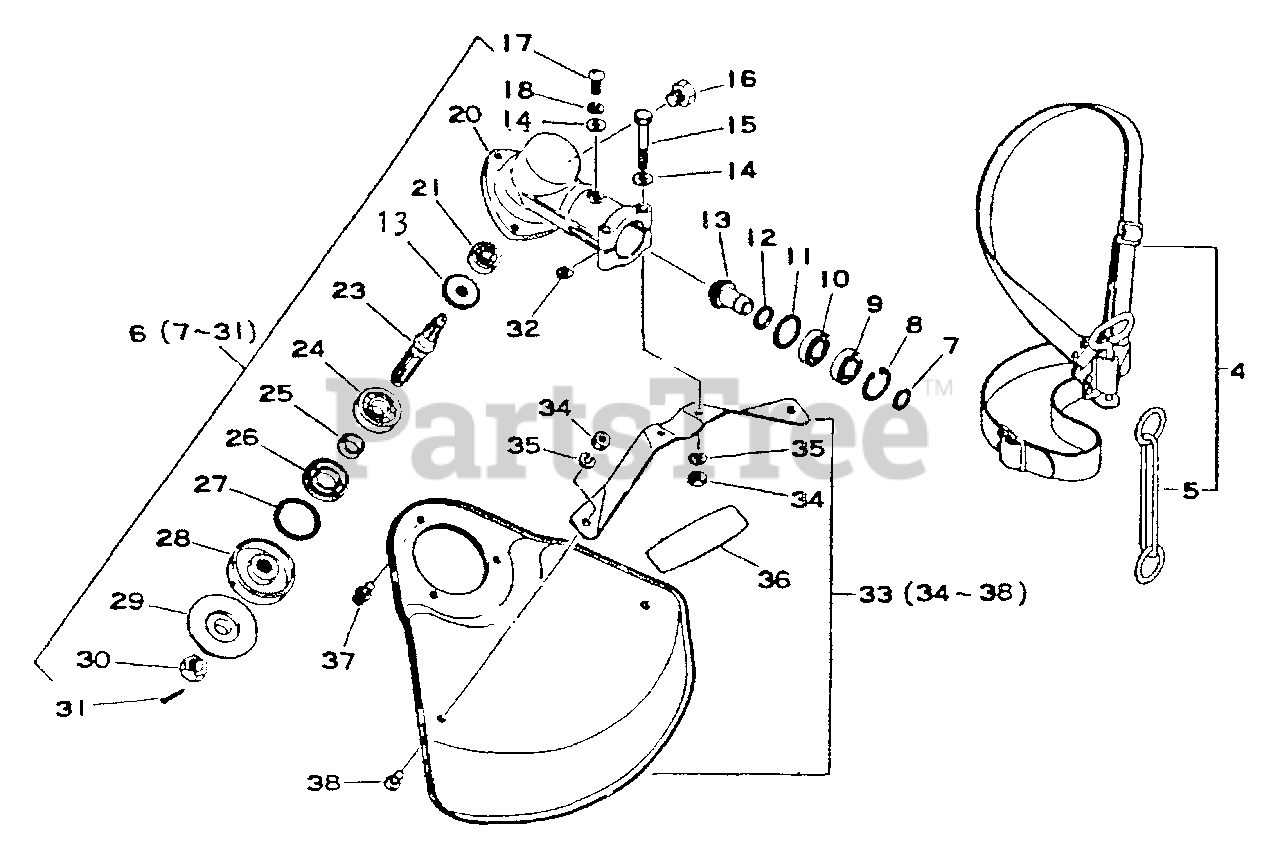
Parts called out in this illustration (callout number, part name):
4	SHOULDER STRAP ASSY
5	HOOK
6	GEAR CASE ASSY
7	RING, SNAP Ø10
8	RING, SNAP Ø22
9	BEARING, BALL 6900Z
10	BEARING, BALL 6900
13	GEAR SET
14	WASHER, FLAT 5.5×10×0.8
15	BOLT 5×35 SP
16	BOLT 8×8 SP
17	SCREW 5×10
18	WASHER, SPRING 5
20	CASE, GEAR
21	BEARING, BALL 626
23	SHAFT, GEAR
24	BEARING, BALL 6000
26	SEAL, OIL
27	RING, SNAP 26
28	PLATE, ADAPTER - UPPER
29	PLATE, ADAPTER - LOWER
31	PIN, COTTER 2×22
33	SHIELD ASSY
34	NUT M5
35	WASHER, SPRING 5
36	LABEL - ECHO
37	SCREW 5×10
38	SCREW 5×16
